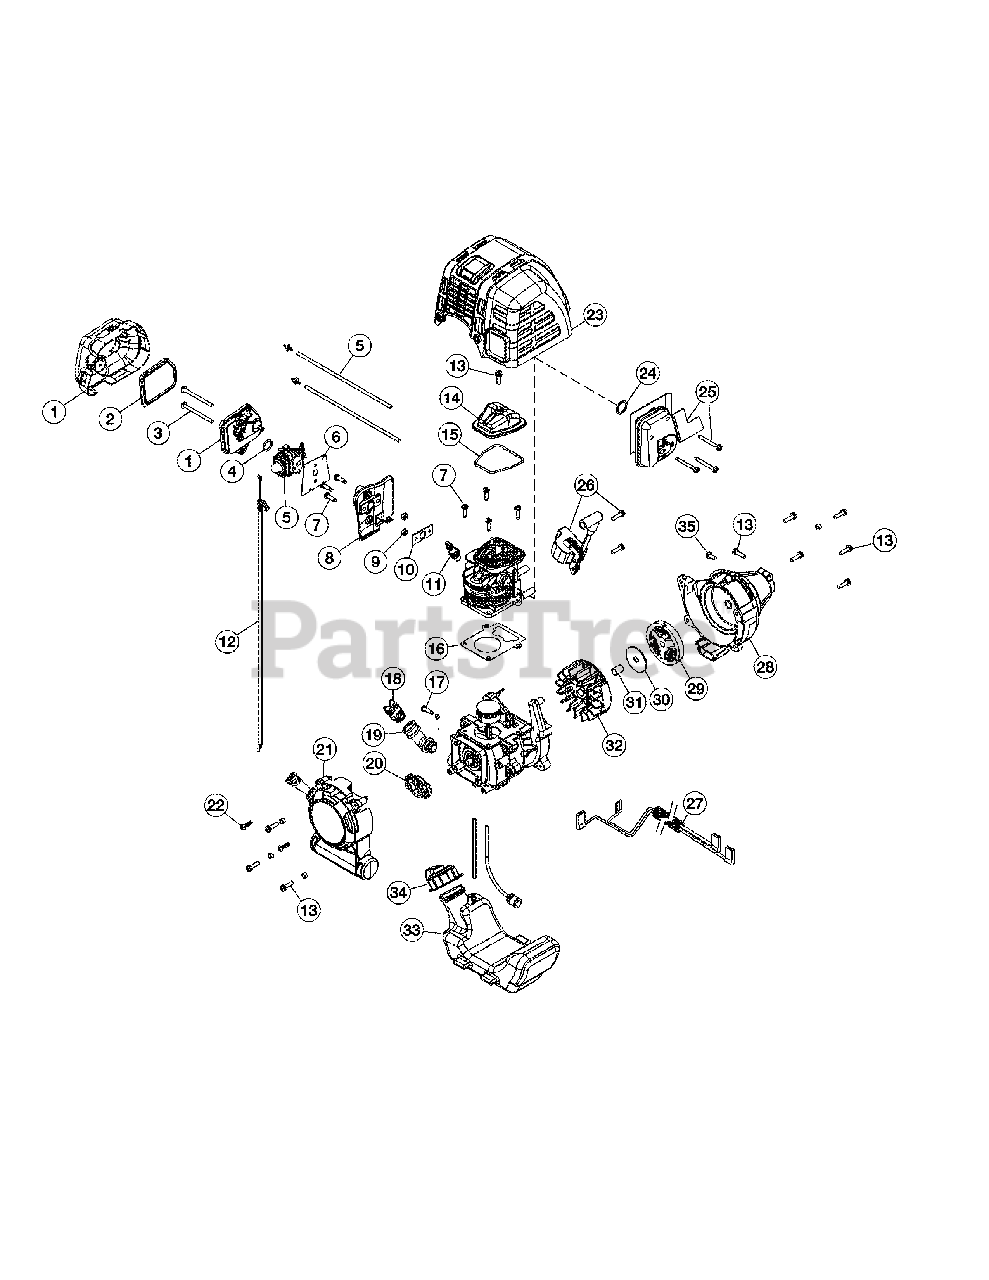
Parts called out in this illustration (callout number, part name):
1	Aircleaner Assembly
2	Air Filter
4	Carburetor O-Ring
5	Carburetor Assembly w/ Fuel Lines
6	Carburetor Gasket
7	Screw
10	Insulator Gasket
11	Spark Plug
12	Throttle Cable
14	Valve Cover
15	Valve O-Ring
16	Cylinder Gasket
18	Oil Plug Assembly
19	Oil fill Tube Assembly
20	Pawl Assembly
21	Rear Starter Cover Assembly
23	Starter Housing
24	Muffler Gasket
25	Muffler Assembly
26	Module Assembly
27	Lead Wires
28	Clutch Cover Assembly
30	Clutch Washer
35	Anti-Rotation Screw
